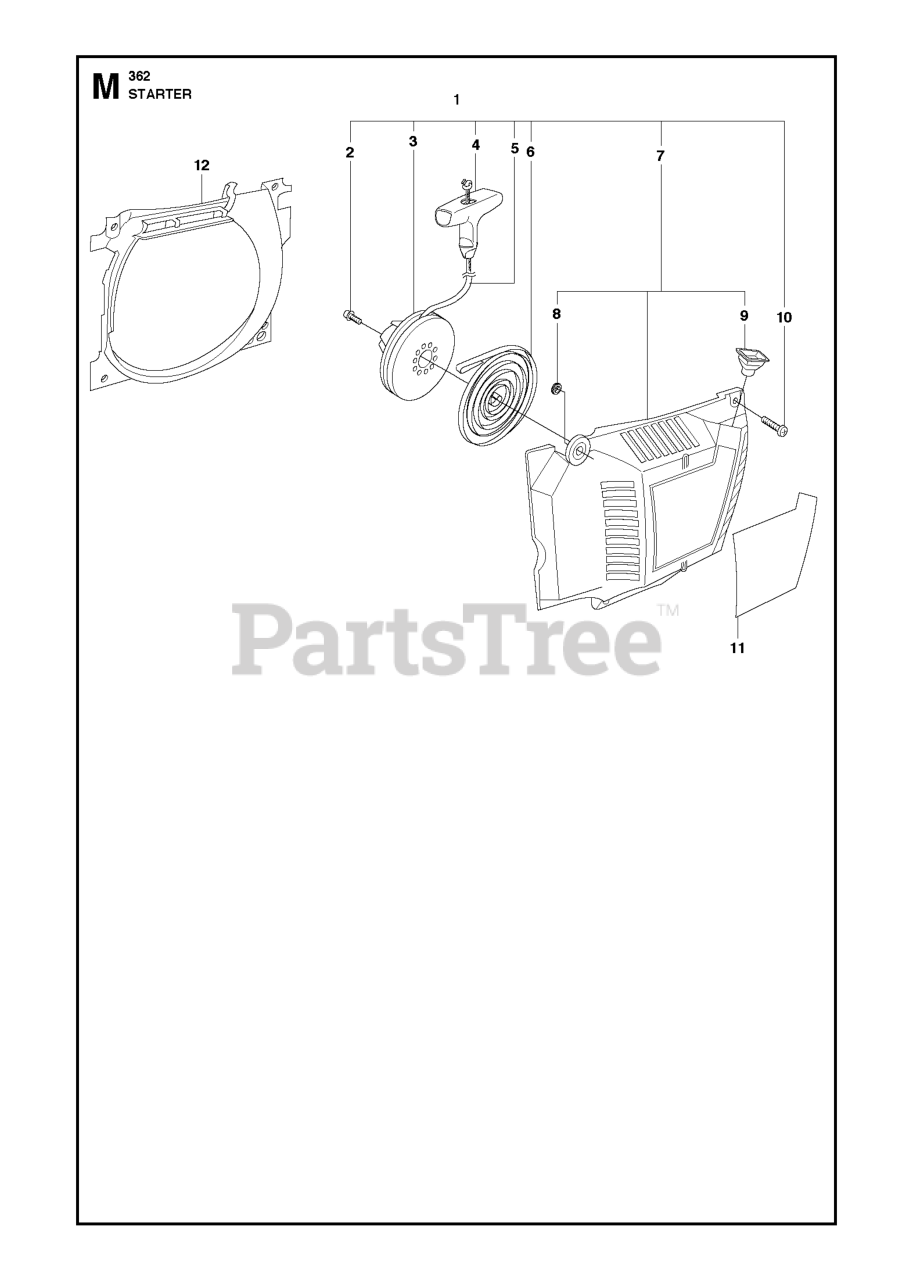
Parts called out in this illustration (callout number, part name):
1	STARTER ASSY
2	SCREW ITXSCFT WASHER PW5.5X16/
3	STARTER PULLEY
4	STARTER HANDLE
5	STARTER CORD
7	STARTER HOUSING
10	SCREW CITXPANMO
12	AIR CONDUCTOR
